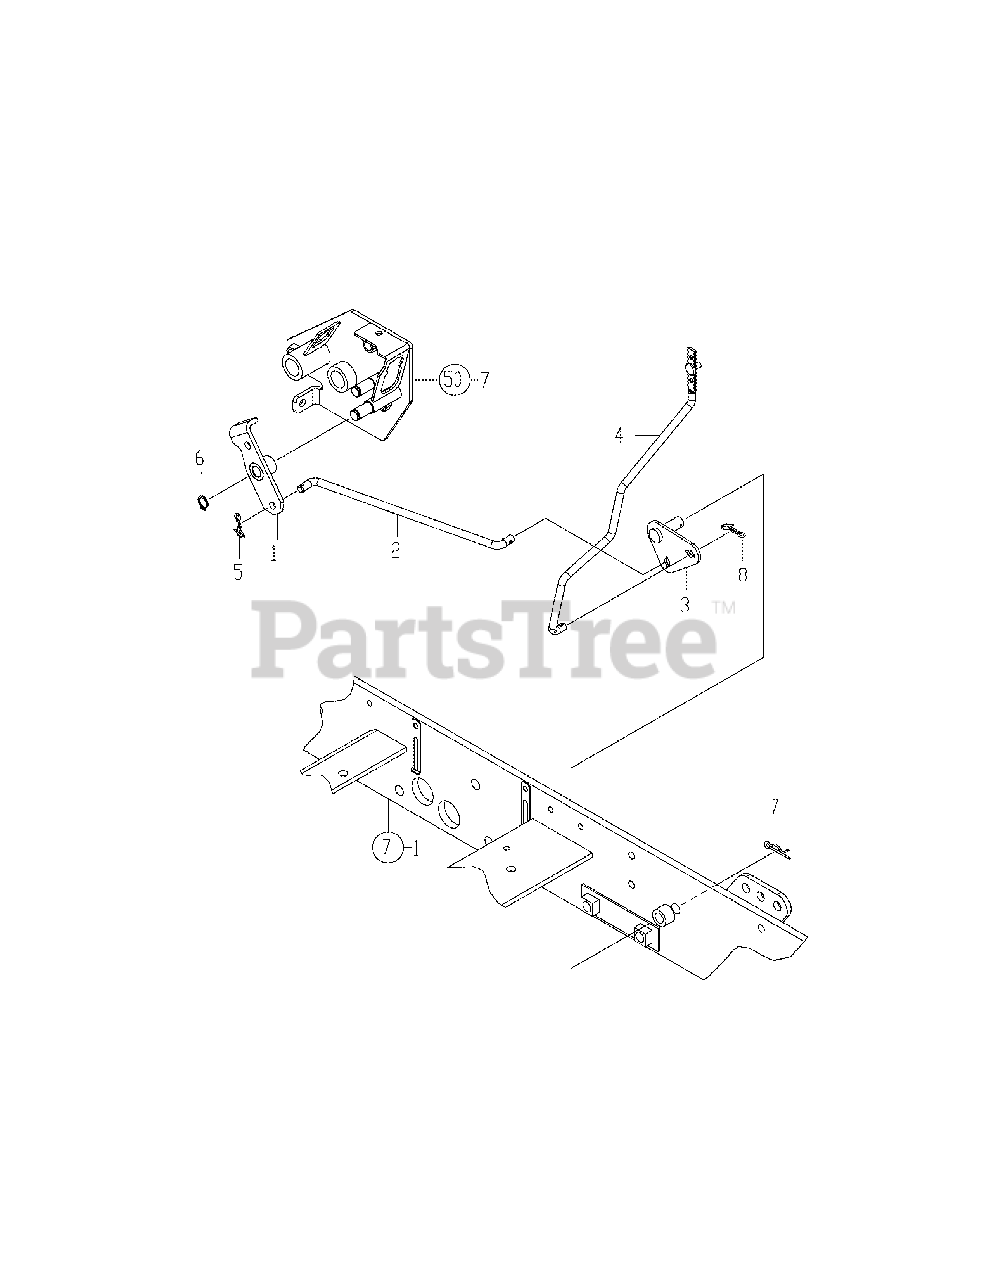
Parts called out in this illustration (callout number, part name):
1	Arm A, Cruise Cmp
3	Link, Cruise Cmp
4	Rod B, Cruise Cmp
4-1	Rod B, Cruise Cmp
5	Pin, Snap
8	Pin 8, Come-Off Snap
